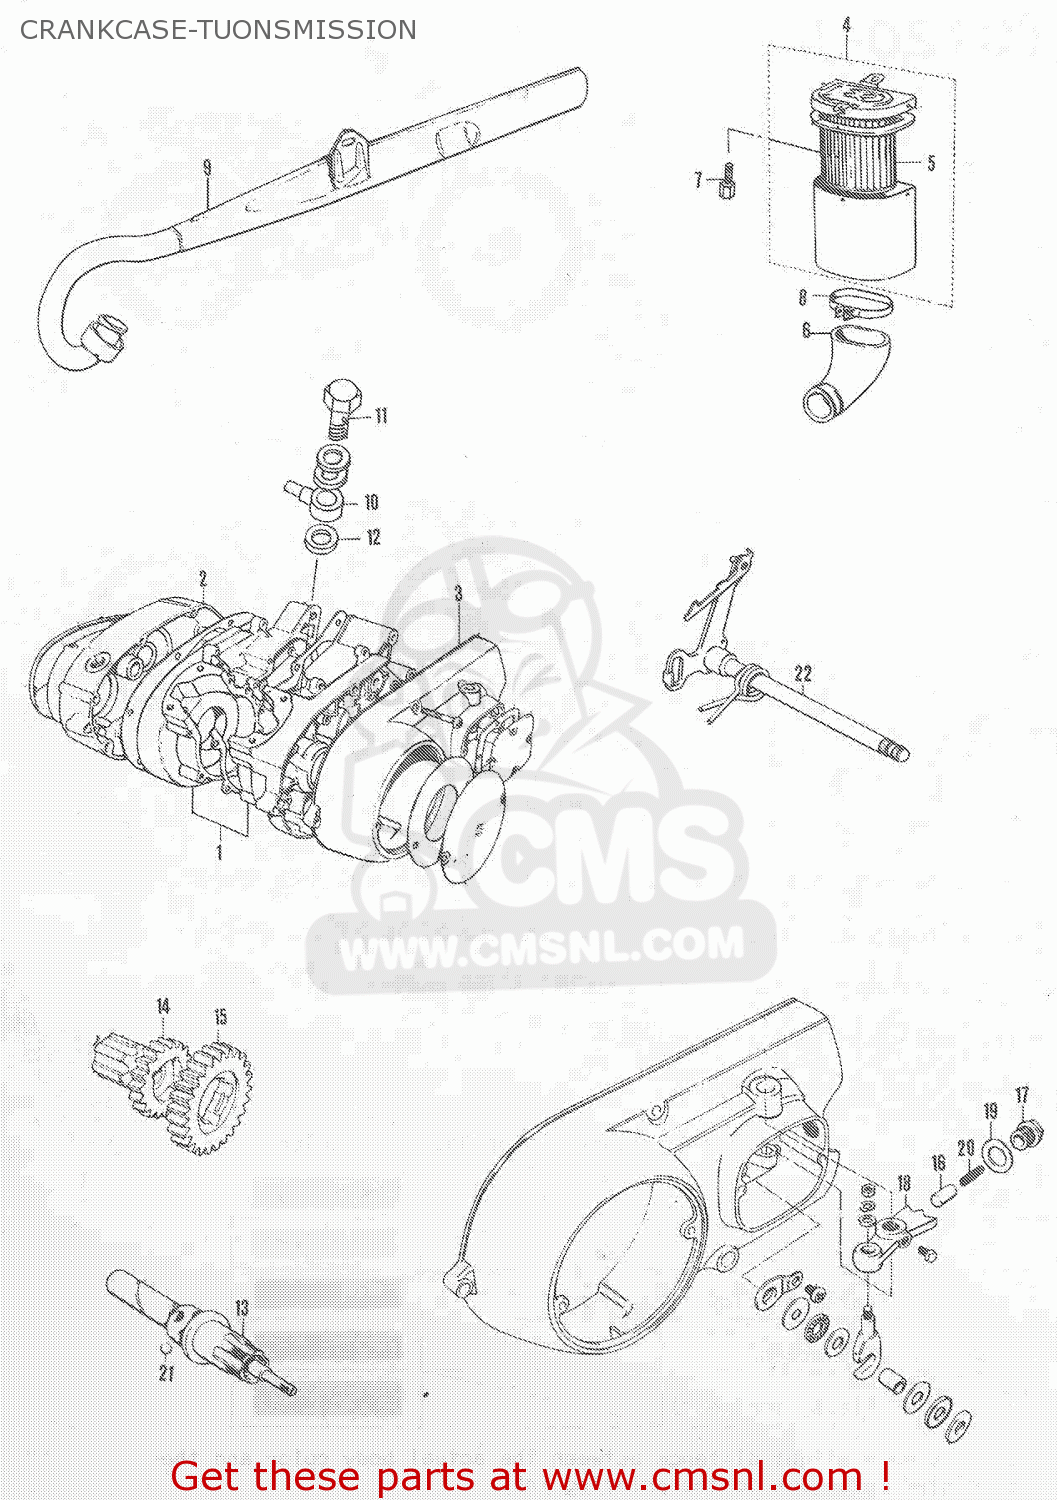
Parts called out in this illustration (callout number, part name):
1	CRANKCASE SET
2	COVER,CLUTCH
3	COVER
4	CLEANER ASSEMBLY,AIR
5	FILTER,AIR CLEANER
6	TUBE,AIR CLEANER OUTLET
7	BOLT
8	CLAMP
9	MUFFLER ASSEMBLY
10	HOSE
11	BOLT UNION
12	GASKET (NAS)
13	SHAFT,DRIVE
14	GEAR,THIRD DRIVEN
15	REDUCTION GEAR
16	STOPPER,GEAR SHIFTING
17	HOLDER,SHIFTING CAM STOPPER
18	ARM,REDUCTION SHAFT
19	WASHER (16.5X42X2.6)
20	SPRING
21	BALL
22	SHAFT,GEAR SHIFT
